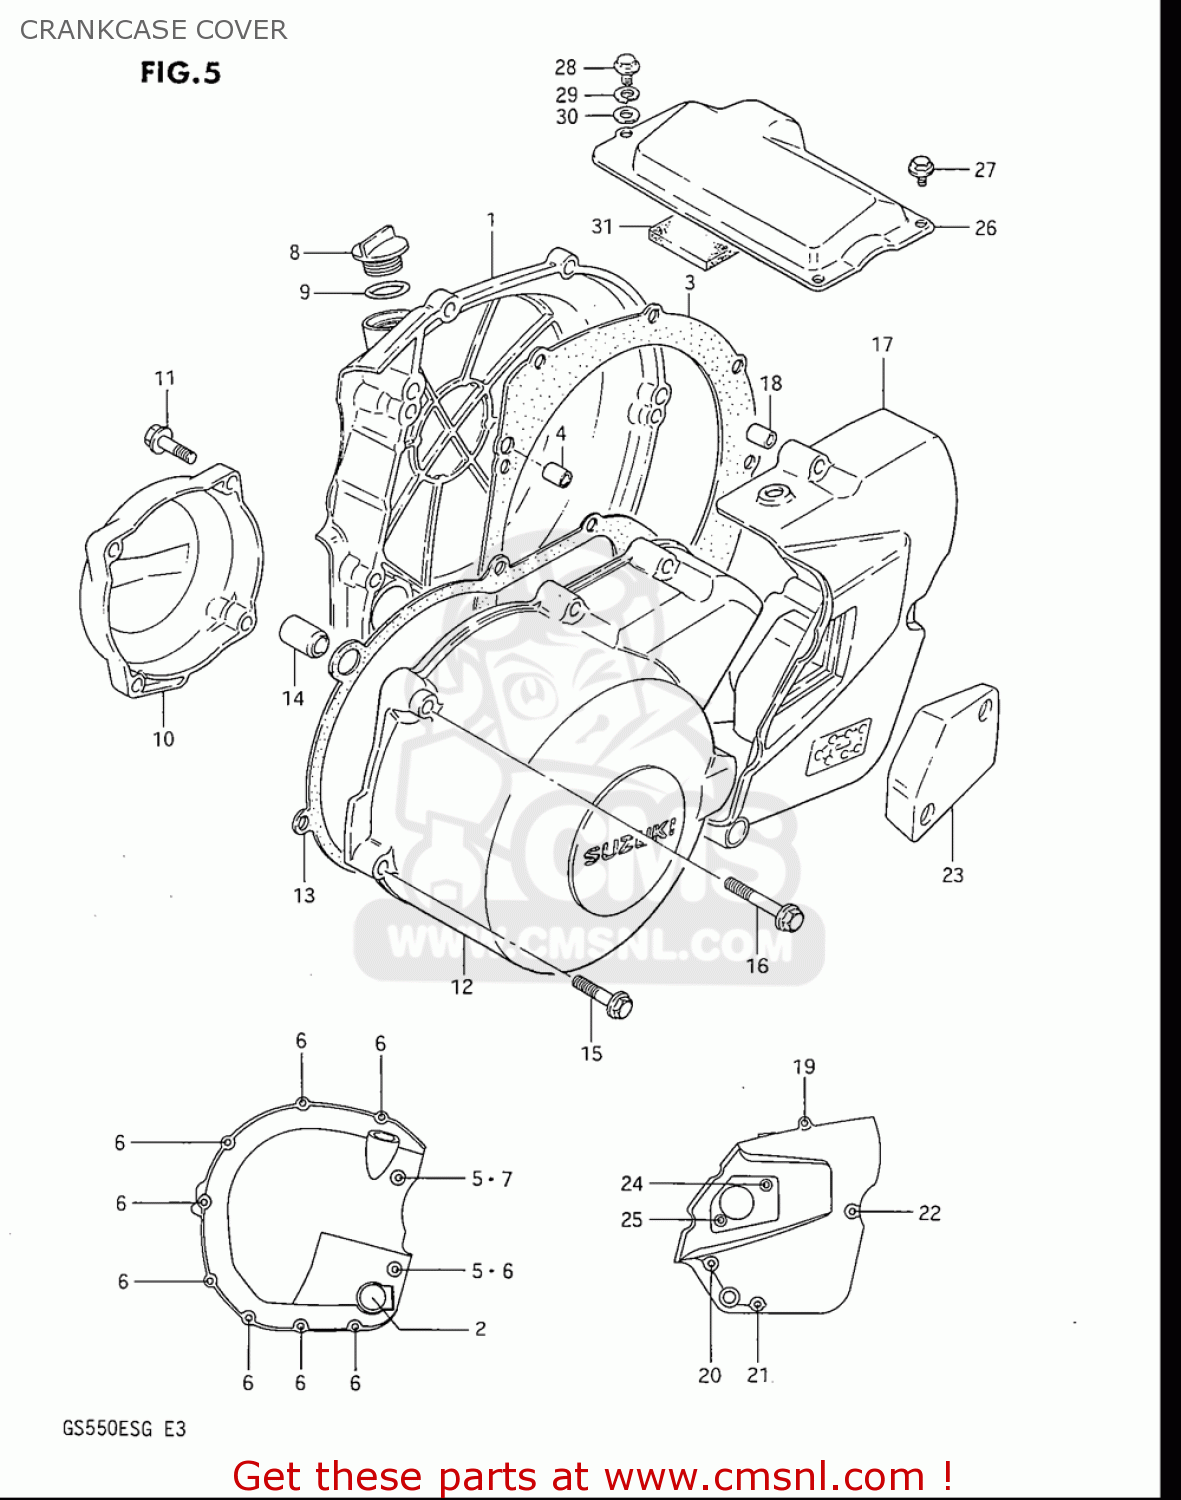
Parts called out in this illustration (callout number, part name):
2	LENS,OIL LEVEL CHECK
3	GASKET,CLUTCH COVER (NAS)
4	PIN
5	GASKET(5.8X13X1.2) (NAS)
6	SCREW
7	BOLT
8	PLUG
9	O RING(D:3.1,ID:16.8)
10	COVER,CONTACT BREAKER
11	SCREW
12	COVER,MAGNETO
13	GASKET,MAGNETO COVER (NAS)
14	PIN(8.4X11X20)
15	BOLT
16	BOLT
18	PIN
19	BOLT
20	BOLT
21	BOLT
22	BOLT
23	CAP,CLUTCH RELEASE ADJUST
24	SCREW
25	SCREW
26	COVER,STARTER MOTOR
27	BOLT
28	BOLT
29	LOCK,WASHER
30	WASHER(5.5X16X1.2)
31	DAMPER,STARTER MOTOR CLUTCH
